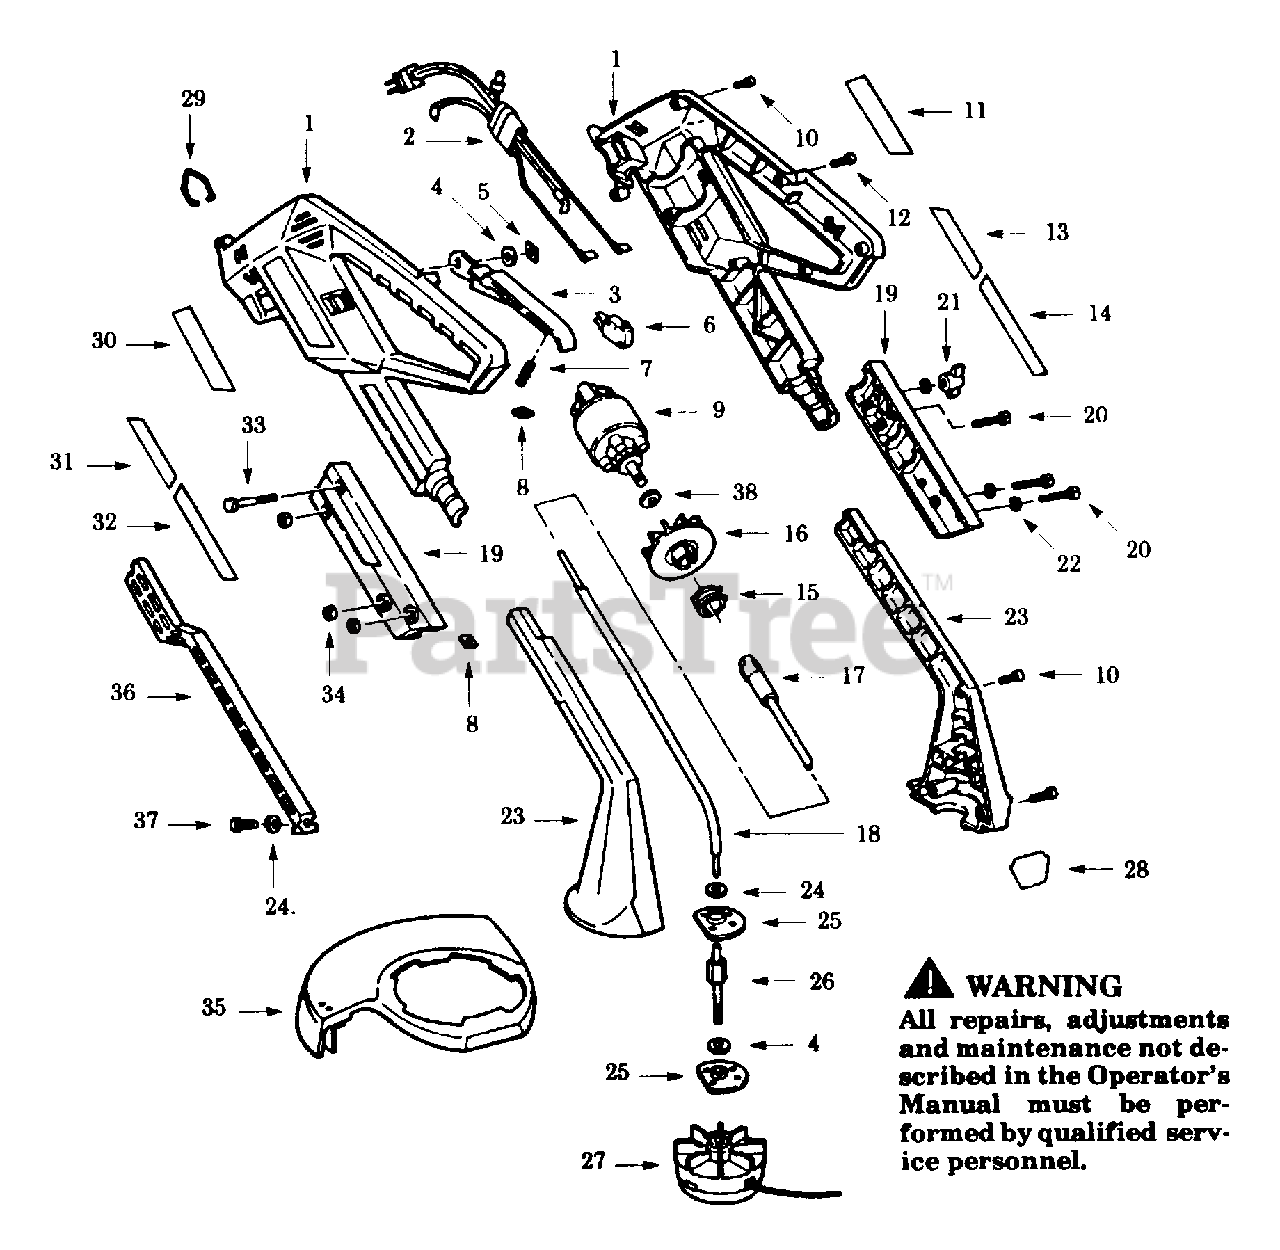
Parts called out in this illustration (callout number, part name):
1	Motor Hsg. Set
2	Harness Ass'y.
5	Push Nut
7	Trigger Spring
8	Square Nut
9	Motor Ass'y.
11	Warning Label (Not a serviceable part)
13	Model No. Label (L) (Not a serviceable part)
14	Logo Label (L)
15	Fan Clamp
17	Flex Shaft Ass'y.
18	Sleeve Tubing
19	Housing Clamp
23	Spindle Housing
25	Bearing Holder Disk
26	Shaft Adapter
27	Cutting Head Ass'y.
28	Start-N-Feed Label (Not a serviceable part)
30	Nameplate Label (Not a serviceable part)
31	Model No. Label (R) (Not a serviceable part)
32	Logo Label (R)
35	Guard Ass'y.
36	Assist Handle
